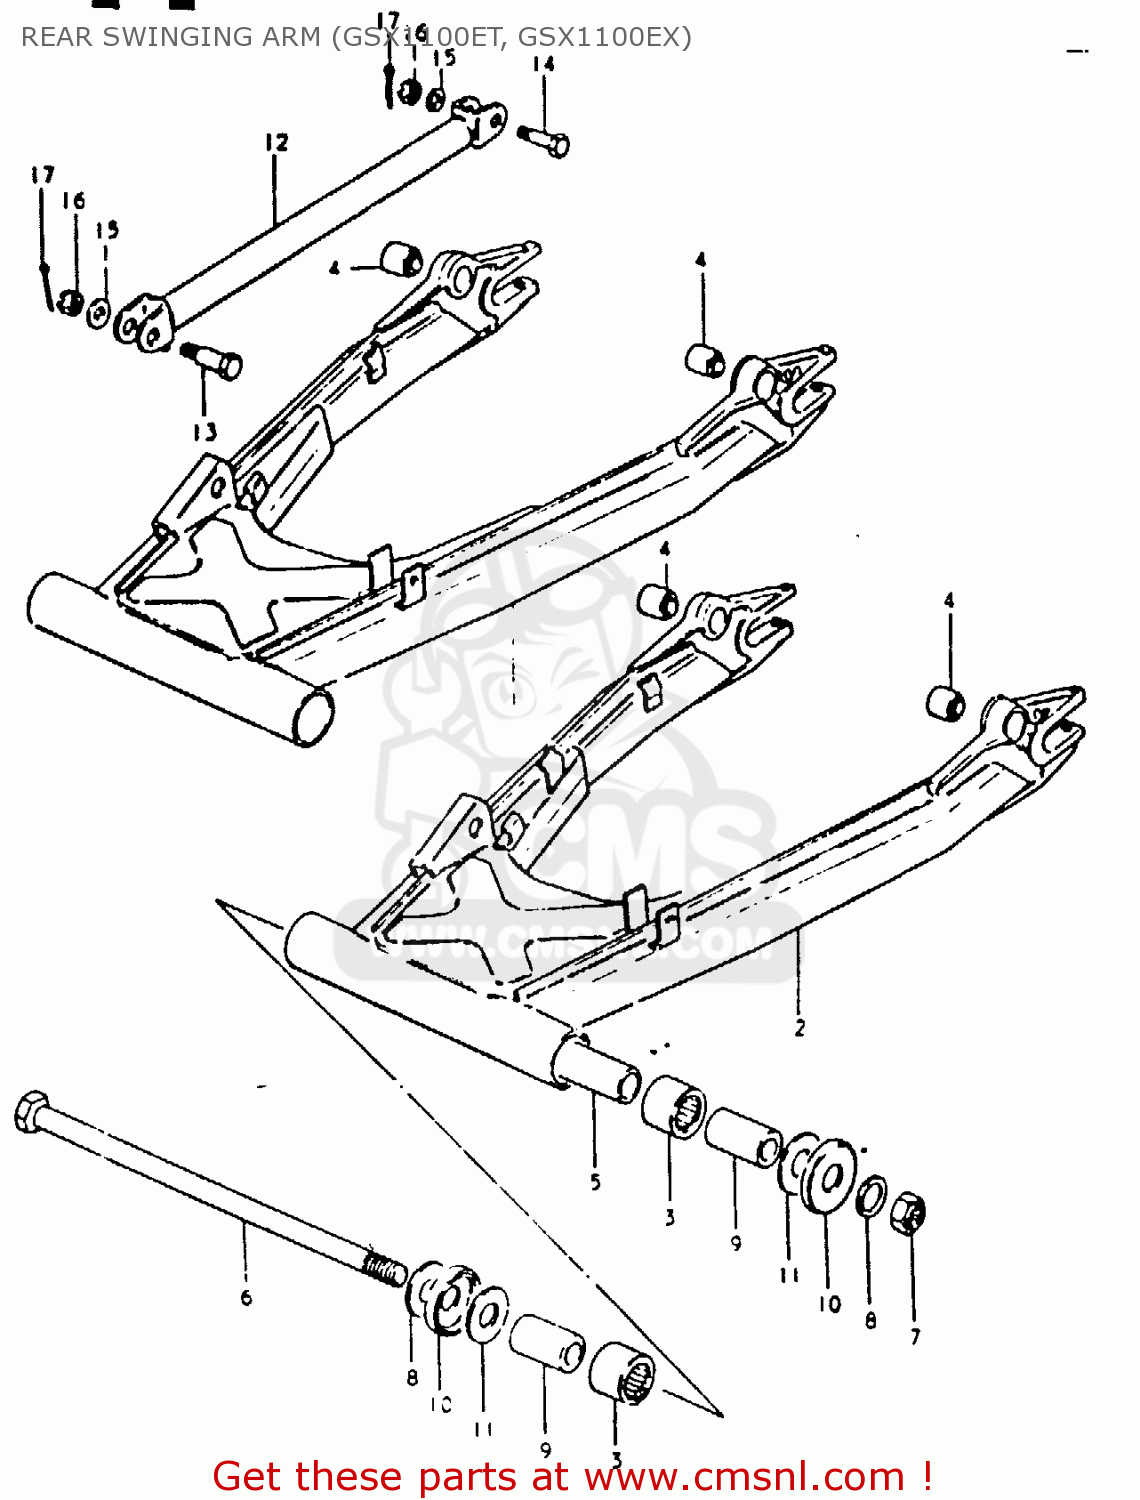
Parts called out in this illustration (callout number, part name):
1	REAR SWINGING ARM SET
2	REAR SWINGING ARM SET
3	BEARING(25X33X30)
4	BUSH
5	SPACER,RR SWGARM PIVOT CTR
6	SHAFT,REAR SWING ARM
7	NUT 16MM
8	WASHER
9	SPACER,RR SWGARM PIVOT
10	COVER, DUST SEAL
11	WASHER
12	TORQUE LINK, REAR
13	BOLT
14	BOLT(10X39)
15	WASHER
16	NUT
17	PIN 20X20
